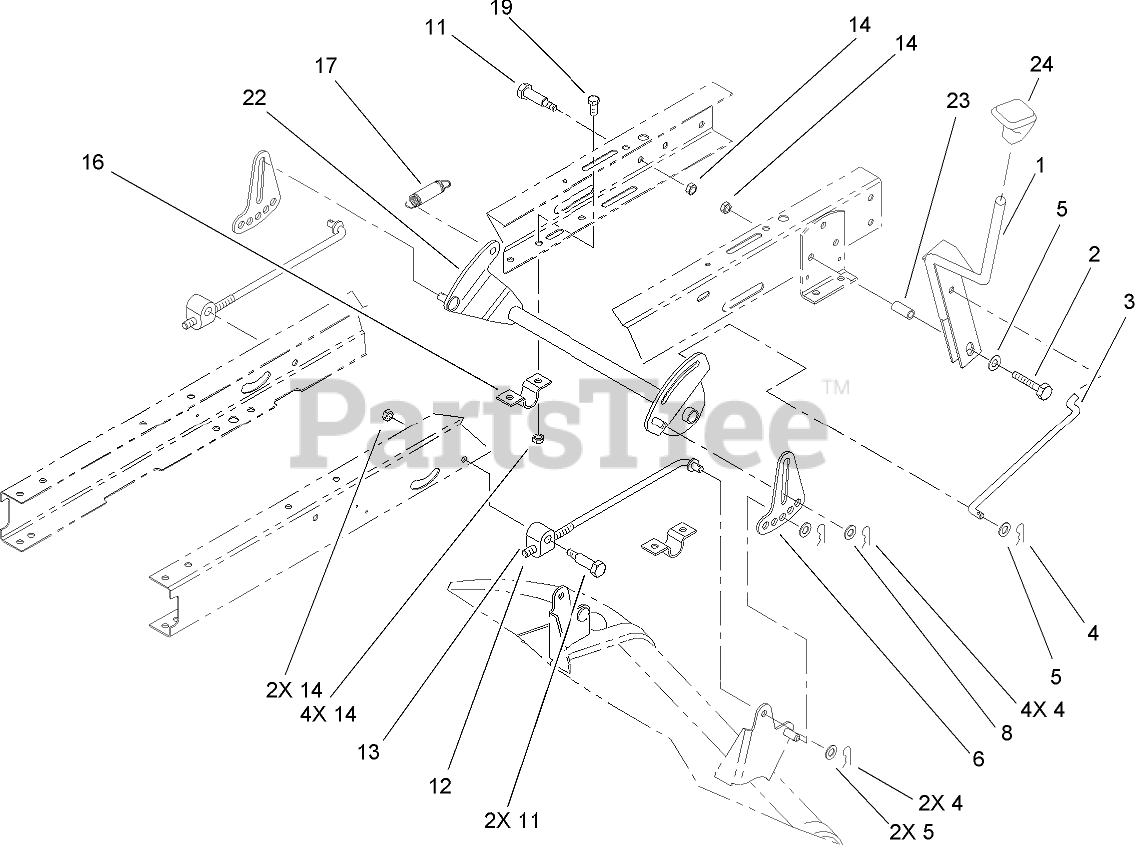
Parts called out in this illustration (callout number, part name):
1	HOC LEVER ASM
2	SCREW-HH
3	LINK-HOC
4	PIN-COTTER
5	WASHER-FLAT
6	LINK-ADJUSTING, HOC
8	WASHER-HARDENED
11	SCREW-SHOULDER, HH
12	ROD-HANGER, REAR
13	TRUNNION-HOC
14	NUT-LOCK, NI
16	CLAMP-PIVOT, HOC
17	SPRING-EXTENSION
19	SCREW-HH
22	PIVOT ASM
23	SPACER
24	KNOB-SHIFT
